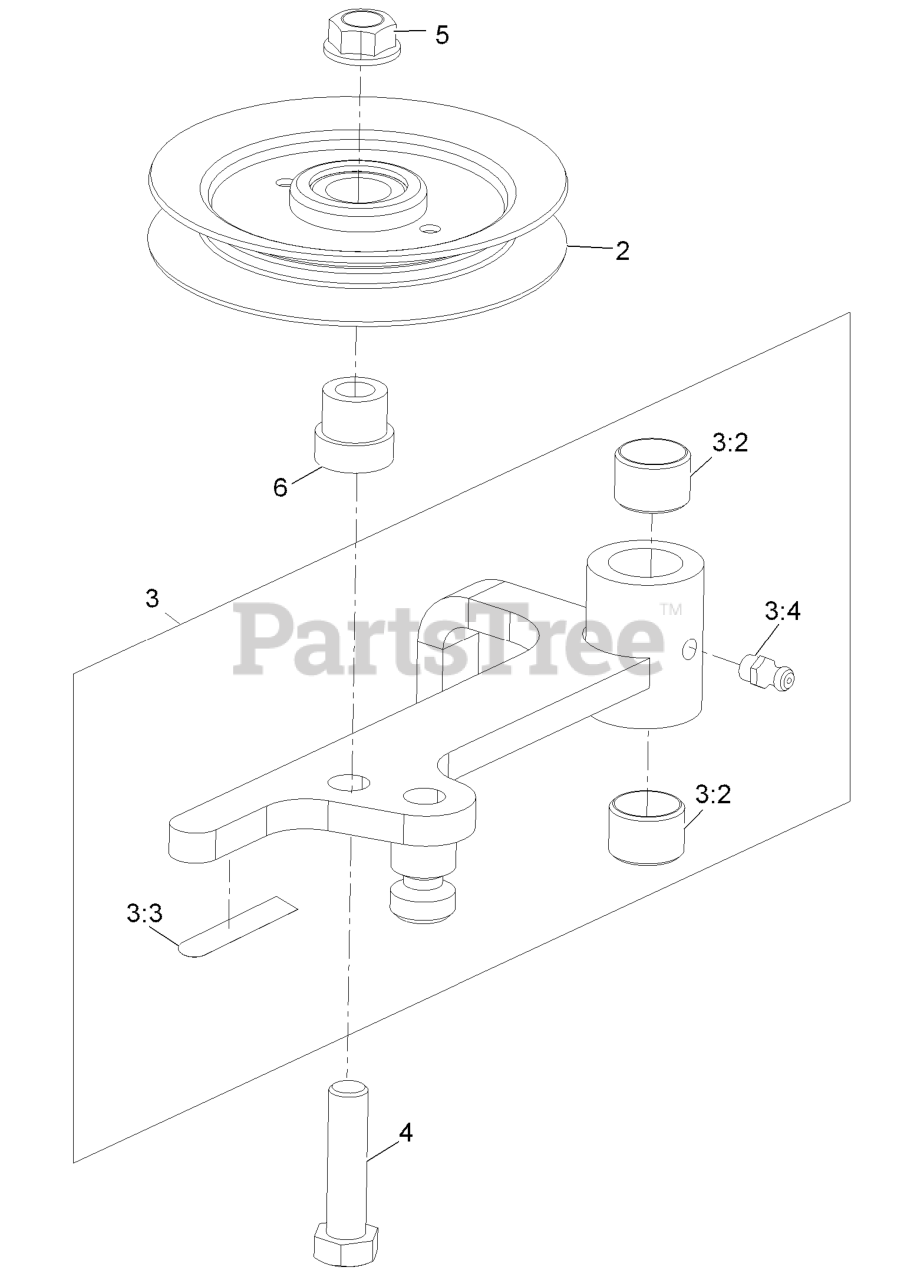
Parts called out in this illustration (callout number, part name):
3	ASM, IDLER ARM - SERVICE
3:2	BUSHING
3:3	DECAL-WARNING
3:4	FITTING-GREASE
4	SCREW-HH
5	NUT-HHF, WHIZ
6	HUB,SPACER
